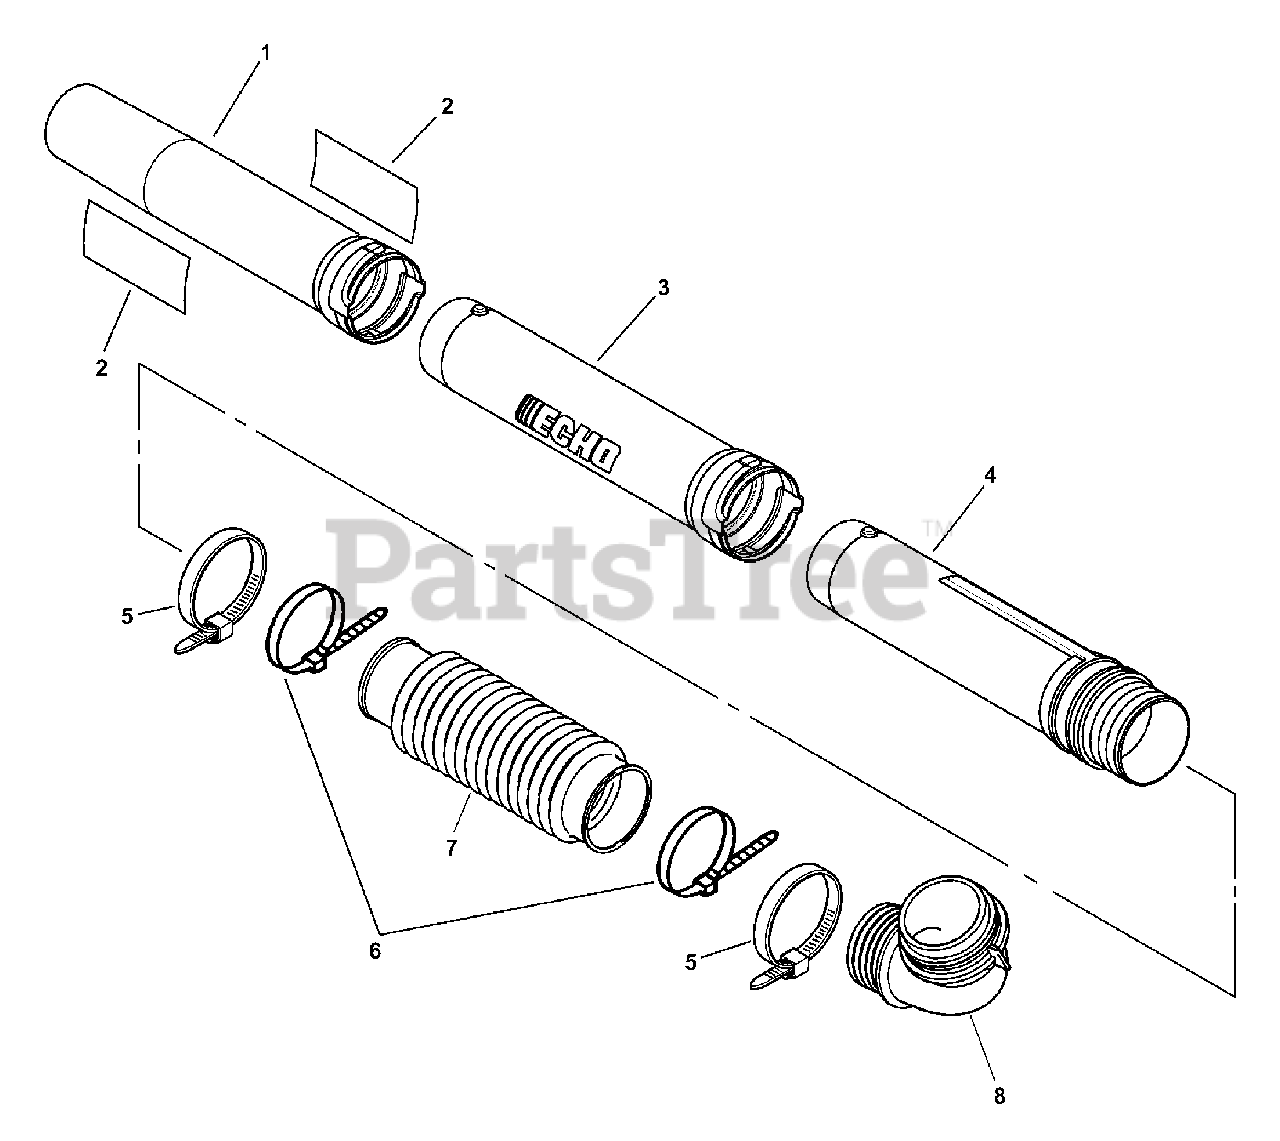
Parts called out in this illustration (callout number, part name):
1	TUBE, BLOWER - STRAIGHT
2	LABEL - ECHO
3	TUBE, BLOWER - STRAIGHT
4	TUBE, BLOWER - SWIVEL
5	CLAMP, HOSE
6	TIE, CABLE - LARGE
7	TUBE, BLOWER - FLEXIBLE
8	TUBE, BLOWER - ELBOW
